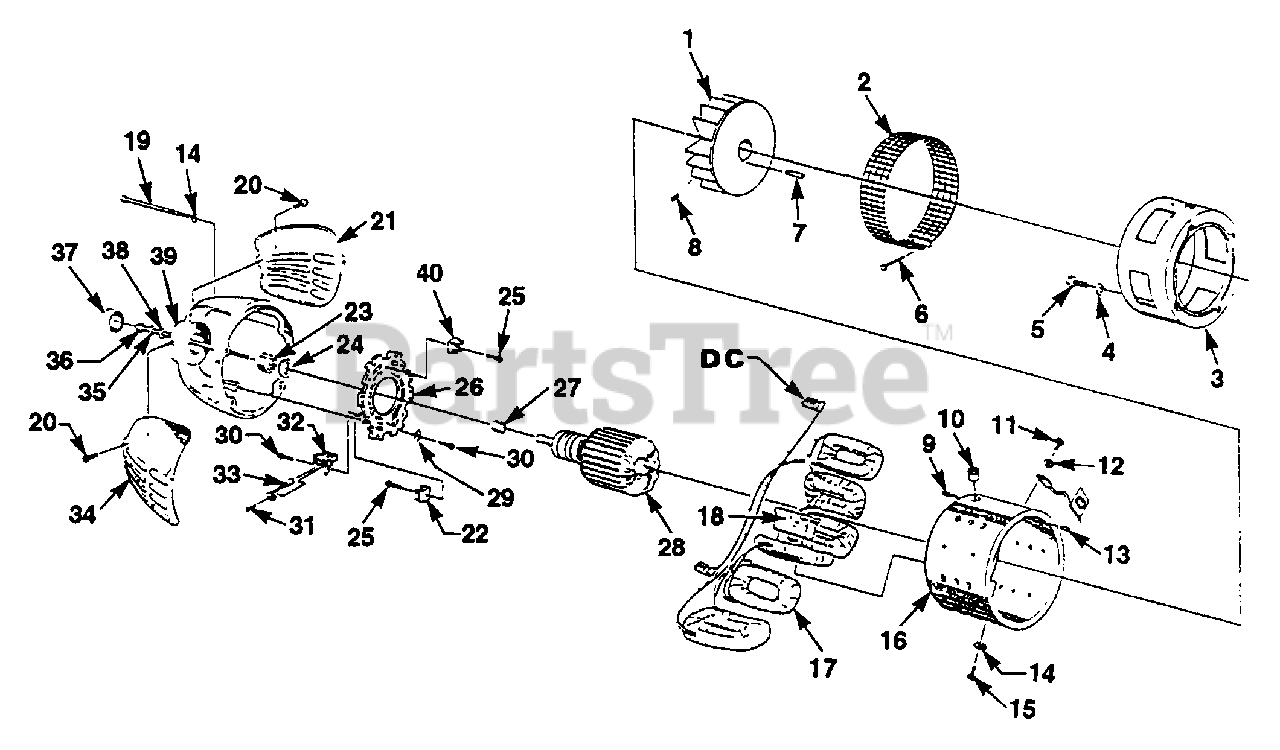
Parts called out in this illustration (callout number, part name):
2	SCREEN - Generator Mtg Ring
3	ADAPTER - Engine
4	WASHER - Lock Int/Ext (3/8)
5	SCREW - Hex Hd (3/8-16 X 7/8")
6	SCREW - Machine Fil. Hd (1/4-20 X 2-1/4")
7	KEY (3/16 X 3/16 X 1)
8	SCREW - Set (1/4-20 X 3/8")
9	PIN - Spirol
10	BUSHING - Flange
11	SCREW - Mach Pan Hd (8-32 X 3/8")
12	WASHER - Lock (#8)
13	PIN - Spirol
14	WASHER - Lock (1/4)
15	SCREW - Cap Hex Hd (1/4-20 X 1")
17	COIL - Field
18	POLE - Piece
19	BOLT - Stator
20	SCREW - Mach Hex Hd (10-24 X 5/8")
21	COVER - Brush Head
22	RECTIFIER 35 AMP
23	BEARING - Roller
24	SEAL - Roller Bearing
25	SCREW - Thread Rolling (8-32 X 2/4")
26	RING - Brush Holder
27	RACE - Inner
28	ARMATURE
29	WASHER - Flat (#8)
30	SCREW - Thread Rolling (8-32 X 1/2")
31	SCREW - Round Hd (8-32 X 3/8")
32	HOLDER - Brush
34	COVER - Brush Head
35	WASHER - Lock (5/16)
36	BOLT - Rotor (5/16-24 X 10-3/4")
37	CAP - Bearing
38	WASHER - Flat
39	HEAD - Brush
40	RECTIVIER - 40 AMP
